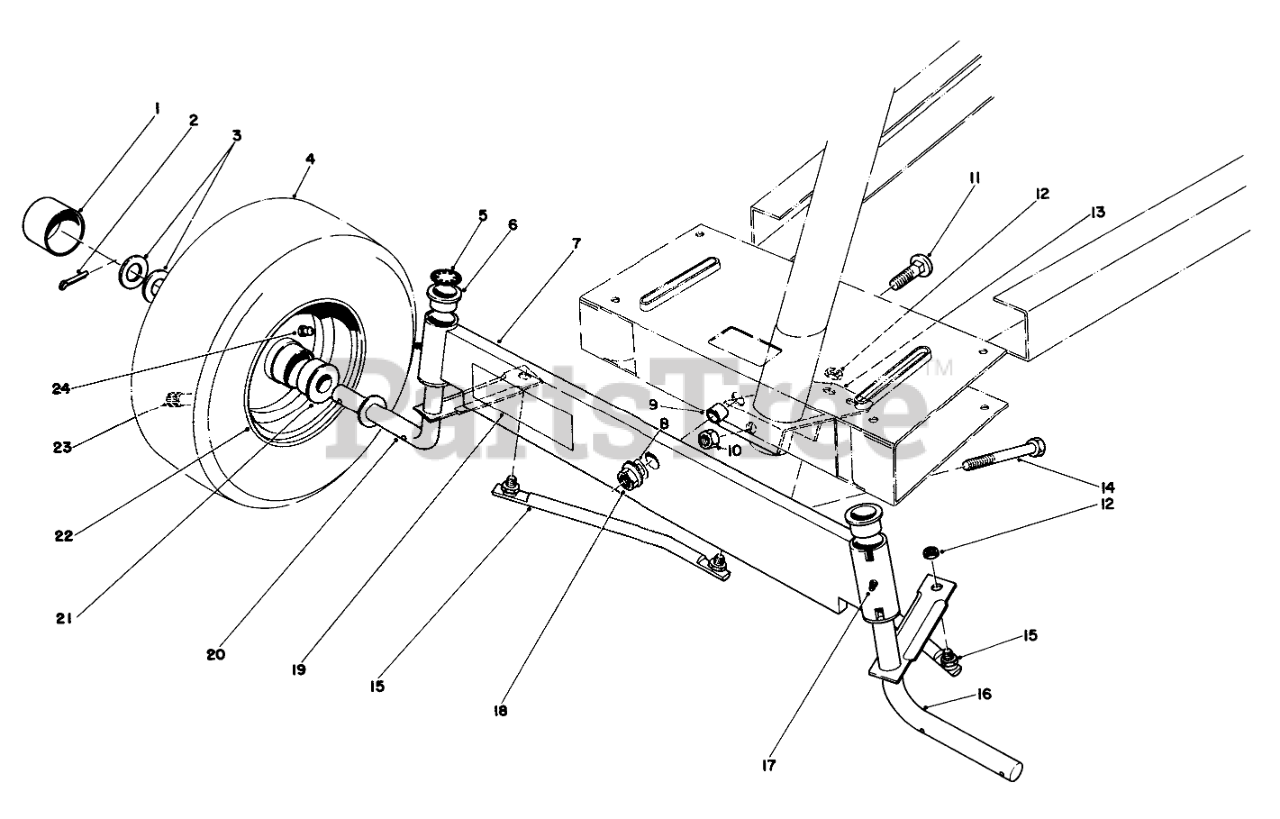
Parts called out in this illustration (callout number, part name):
1	Hub Cap
2	PIN-COTTER
3	WASHER-FLAT
4	Tire
5	RING-RETAINING
6	BUSHING
7	Front Axle
8	WASHER-THRUST
9	FRONT AXLE SPACER
10	NUT-LOCK, CONE
11	SCREW-CARR
12	NUT-LOCK, NI
13	Lever Steering
14	SCREW-HH
15	TIE ROD ASM
16	Spindle L.H.
17	GREASE FITTING
18	NUT-HF
19	Decal-Warning
20	SPINDLE WA RH
21	BUSHING
23	STEM-VALVE
24	FITTING-GREASE
